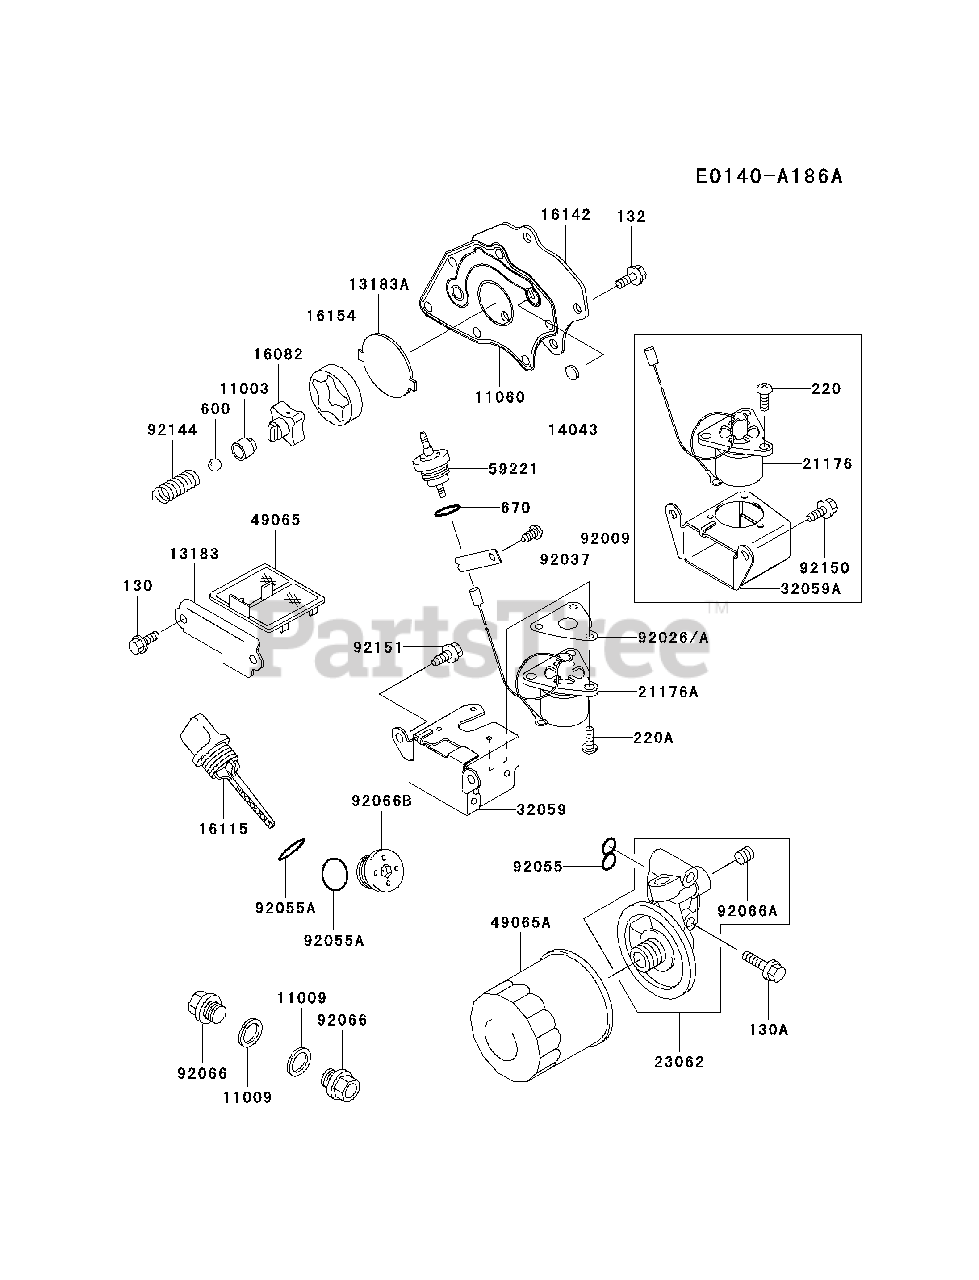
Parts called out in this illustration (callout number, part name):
130A	BOLT-FLANGED
132	BOLT-FLANGED-SMALL
220	SCREW-PAN-CROS
220A	SCREW-PAN-CROSS
600	BALL-STEEL
